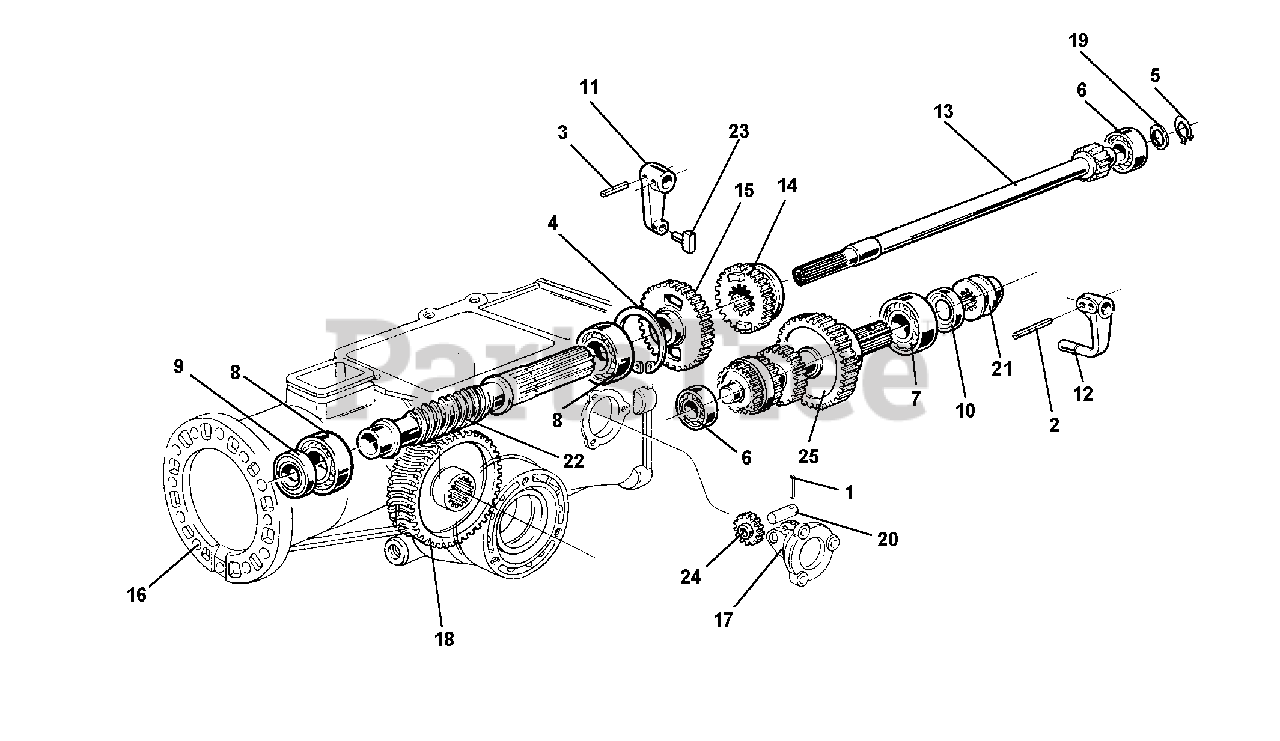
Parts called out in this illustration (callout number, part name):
1	PIN, LOCKING 2.5 X 22 DIN 1481
2	LOCKING PIN 4 X 20 SPIRAL
3	LOCKING PIN 4 X 24 SPIRAL
4	CIRCLIP, INTERN D 52
6	BEARING 15 X 35 X 11 6202
7	BEARING 20 X 47 X 14 6204
8	BEARING 25 X 52 X 15 6205
9	SEAL, OIL 15 X 40 X 10 STANDARD
10	SEAL, OIL 20 X 35 X 7 STANDARD
11	LEVER, SPEED CHG SLDG GR
12	SLIDE LEVER
13	CLUTCH SHAFT
14	SLIDING GEAR
15	I SPEED WHEEL
16	HOUSING BODY
17	REVERSE SPEED FLANGE
18	GEAR Z 49, LH MOTOR MOWER
19	WASHER 15.1 X 25 X 2
24	REVERSE SPEED GEAR
25	P.T.O. SHAFT
